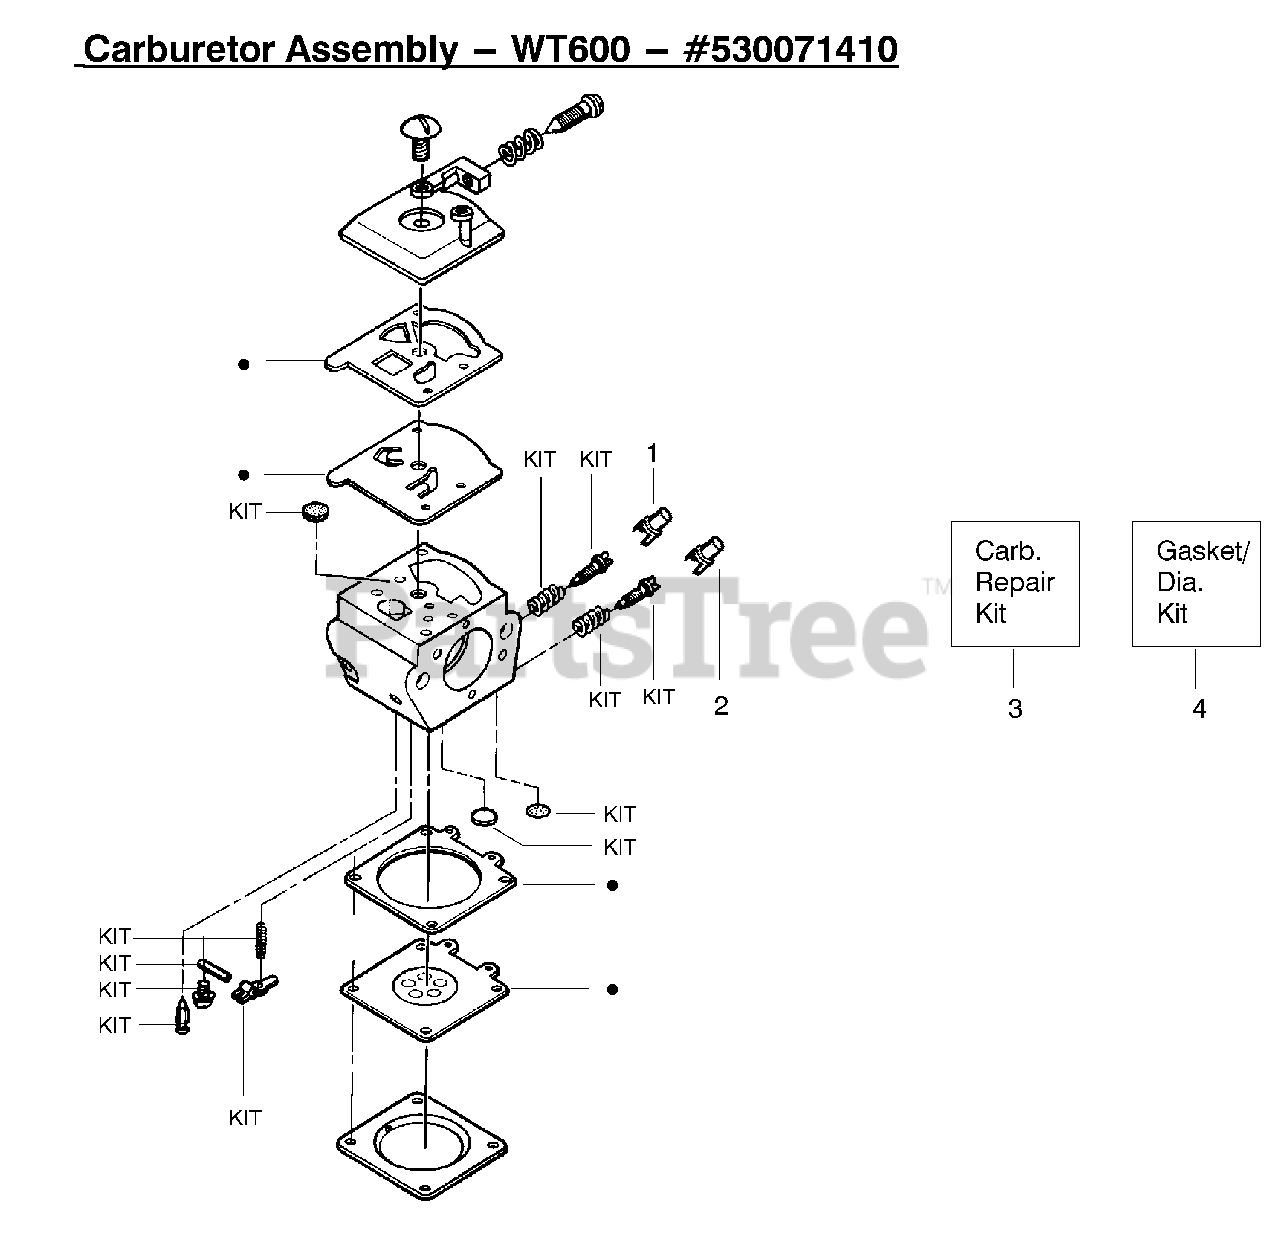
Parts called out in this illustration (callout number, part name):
1	Limiter Cap-High
2	Limiter Cap-Low
3	Kit-Carburetor Repair
4	Kit-Gasket Diaphragm
